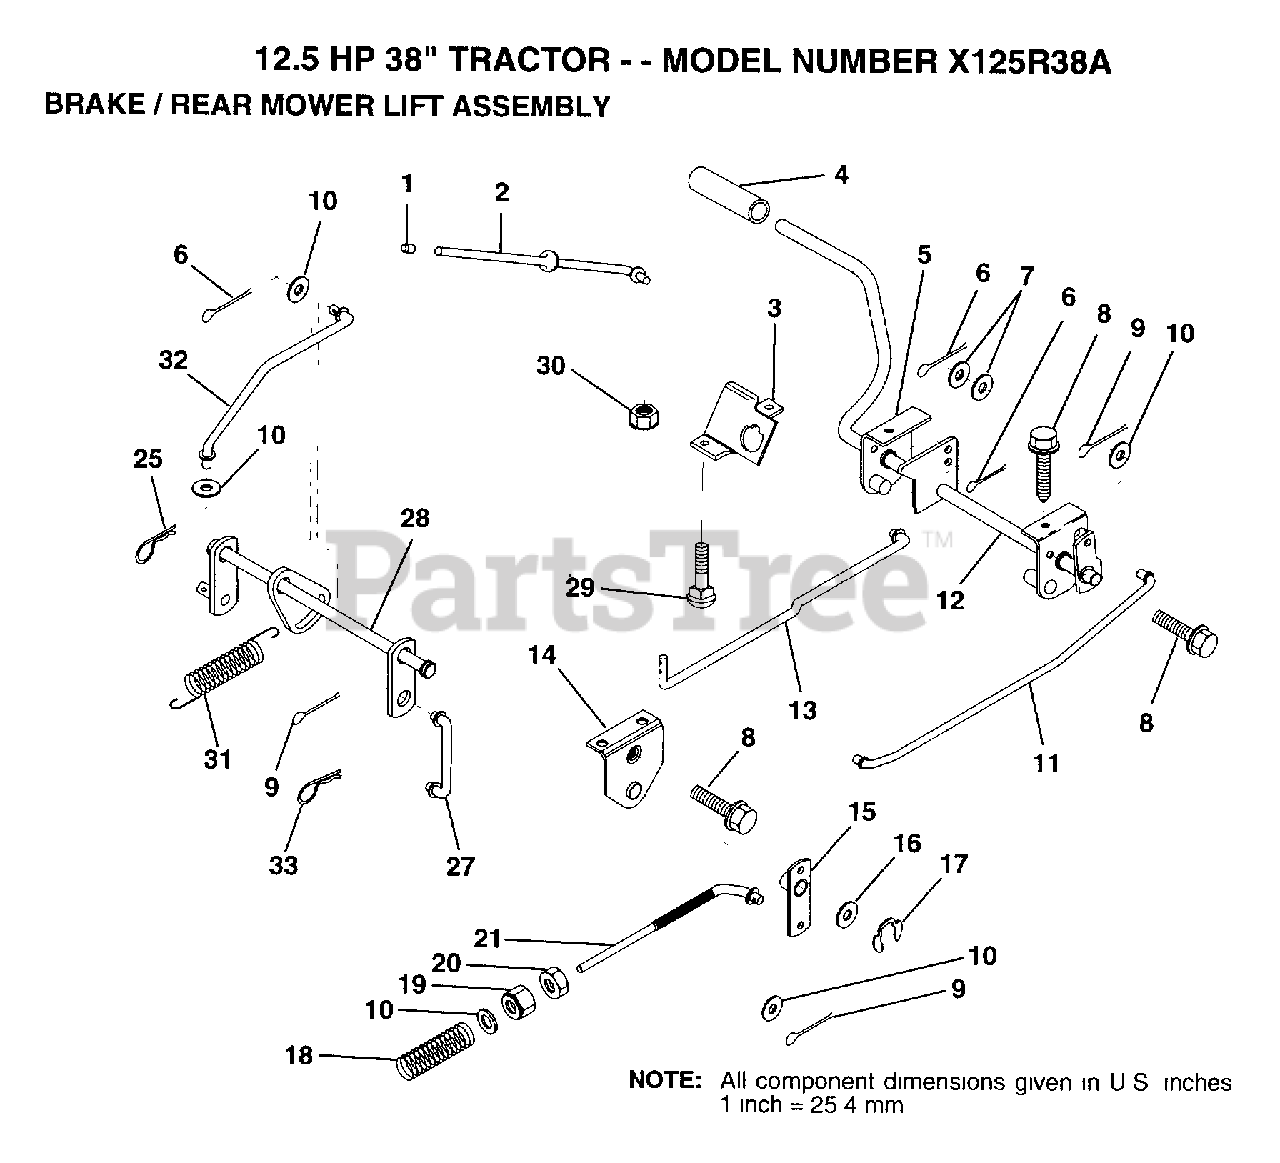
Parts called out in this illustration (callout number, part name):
1	PLUNGER CAP T
2	"ROD,PARK BRAKE"
3	"BRKT,PARK BRAKE"
4	PEDAL COVER T
5	BRK ASM CLUT LH
7	WASHER
8	SCREW LT
9	COTTER PIN
10	WASHER
11	"ROD,FRT BRAKE"
12	ASM CLUTCH/BRK PD
13	"ROD,CLUTCH"
14	"BRKT,LIFT SHAFT"
15	BRAKE PIVOT ARM
16	WASHER T
17	KLIP RING
18	SPRING ROD LT
19	NUT
25	SPRING.RETAINER
27	LINK LIFT REAR LR
28	LIFT ASM MWR RE
31	COUNTER SPRING
32	LINK LIFT LEVER
